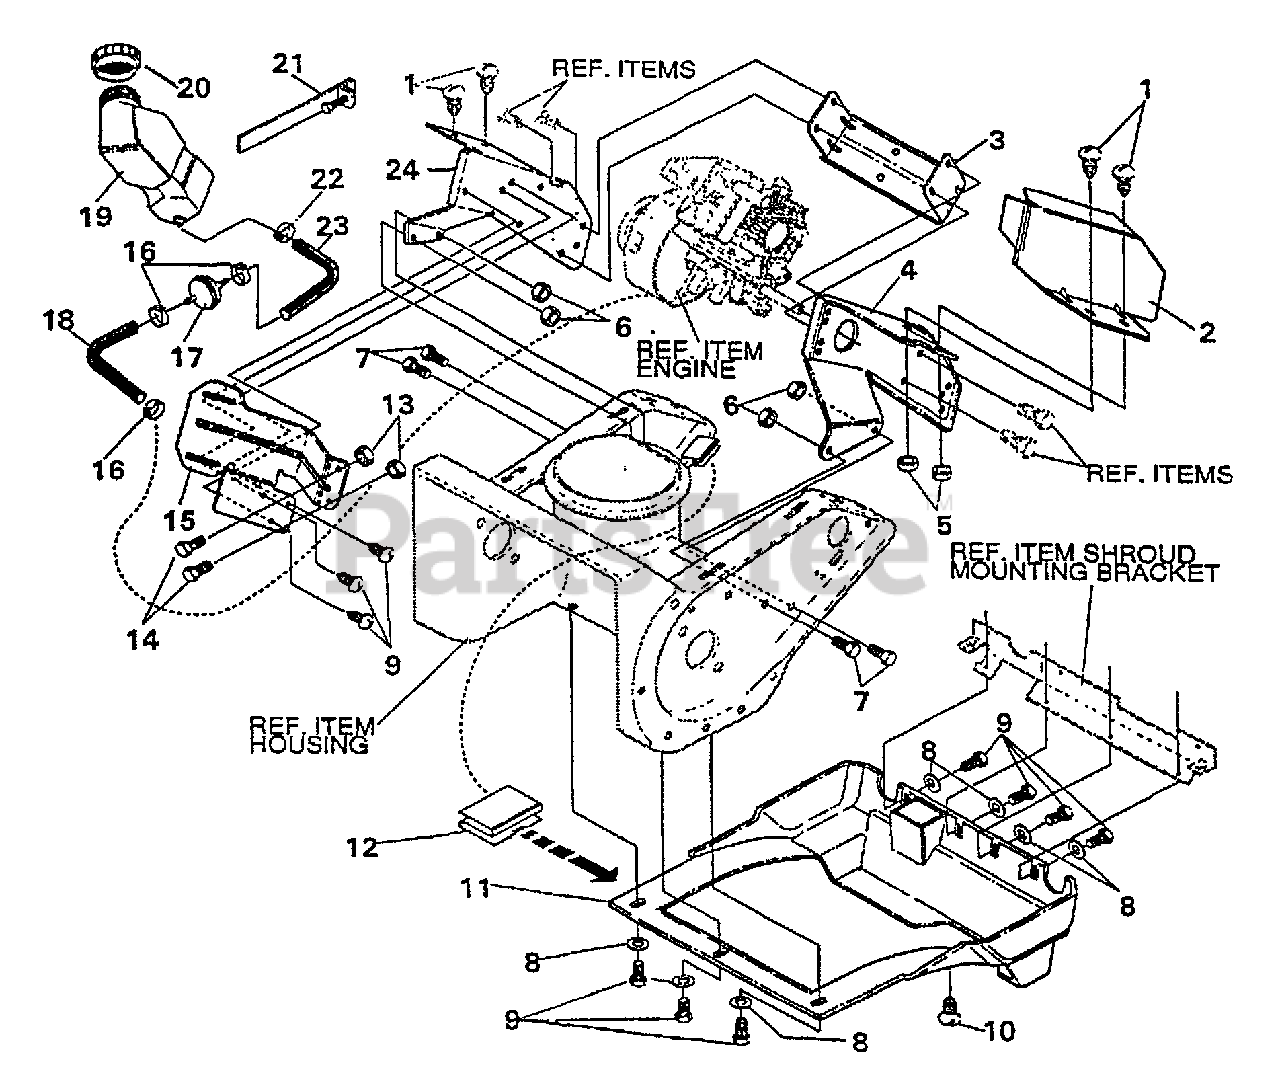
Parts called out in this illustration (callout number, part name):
1	SCREW - 1/4-20×0.63"
2	SHIELD, HEAT
3	SUPPORT, FRAME
4	PLATE, REAR MOUNT -- LEFT
5	NUT, 1/4"-20
6	NUT, 5/16"-18
7	SCREW - 5/16-18 X0.50" -- HEX HEAD CAP
8	WASHER
9	SCREW - 10-24×0.63" -- PAN HEAD
10	SCREW - 10-16×0.50"
11	SHROUD, BOTTOM
12	CLIP
13	NUT
14	SCREW - 10×24×0.50" -- HEX HEAD MACHINE
15	BRACKET, FUEL TANK
16	CLAMP, HOSE
17	FILTER
18	TUBING, GAS LINE 30"
19	TANK, FUEL
20	CAP, FUEL
21	CLAMP, WORM DRIVE
22	CLAMP, HOSE
23	TUBING, GAS LINE 8"
24	PLATE, REAR MOUNT -- RIGHT
